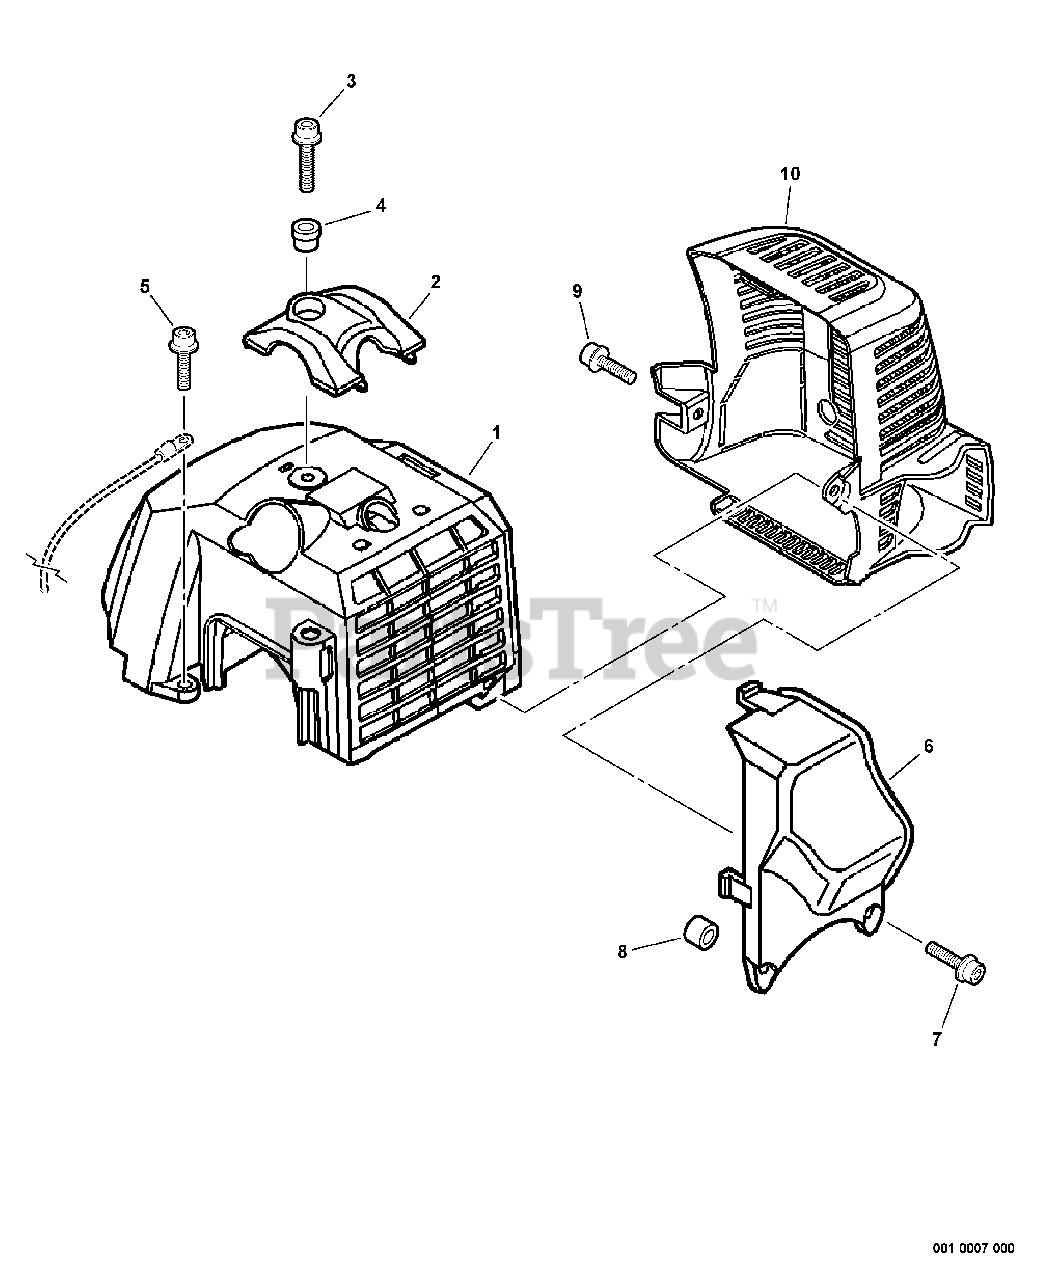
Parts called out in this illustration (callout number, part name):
1	COVER, ENGINE - GRAY
2	GUARD - TOP
3	SCREW - 5X20
4	COLLAR - 5
5	SCREW - 5X12
6	DEFLECTOR, EXHAUST
7	SCREW - 5X25
9	SCREW - 5X12
10	COVER, EXHAUST
